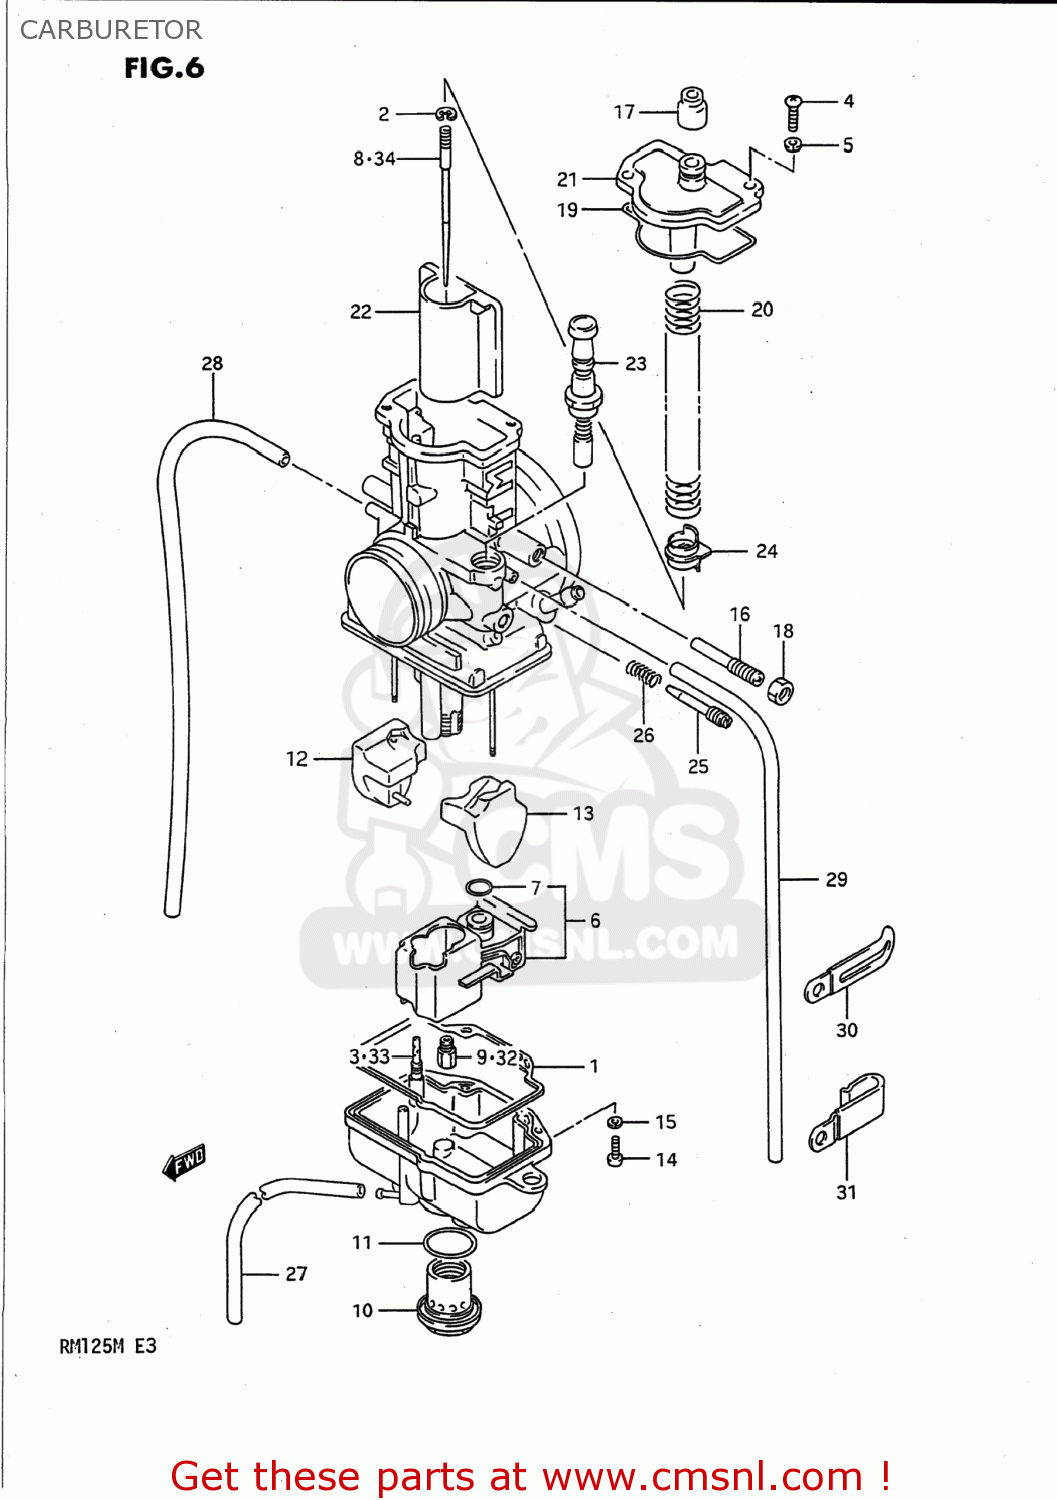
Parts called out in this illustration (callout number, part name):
1	O RING,FLOAT CHAMBER
2	CLIP,NEEDLE
3	JET,PILOT(55)
4	SCREW
5	LOCK WASHER
6	VALVE ASSY,NEEDLE
7	O-RING,NEEDLE VALVE
8	NEEDLE,JET(6AEJ02-65)
9	JET,MAIN(330)
10	CAP,DRAIN
11	O RING
12	FLOAT,R
13	FLOAT,L
14	SCREW
15	LOCK WASHER
16	ADJUSTER
17	CAP
18	NUT
19	O RING,TOP CAP
20	SPRING
21	CAP,TOP
22	VALVE,PISTON
23	PLUNGER ASSY
24	RING
25	SCREW,AIR
26	SPRING
27	HOSE
28	HOSE(3.5X6.5X600)
29	HOSE(3.5X6.5X600)
30	CLAMP
31	CLAMP
32	JET,MAIN(290)
33	JET,PILOT(45)
34	NEEDLE,JET(6AEJ02-63)
